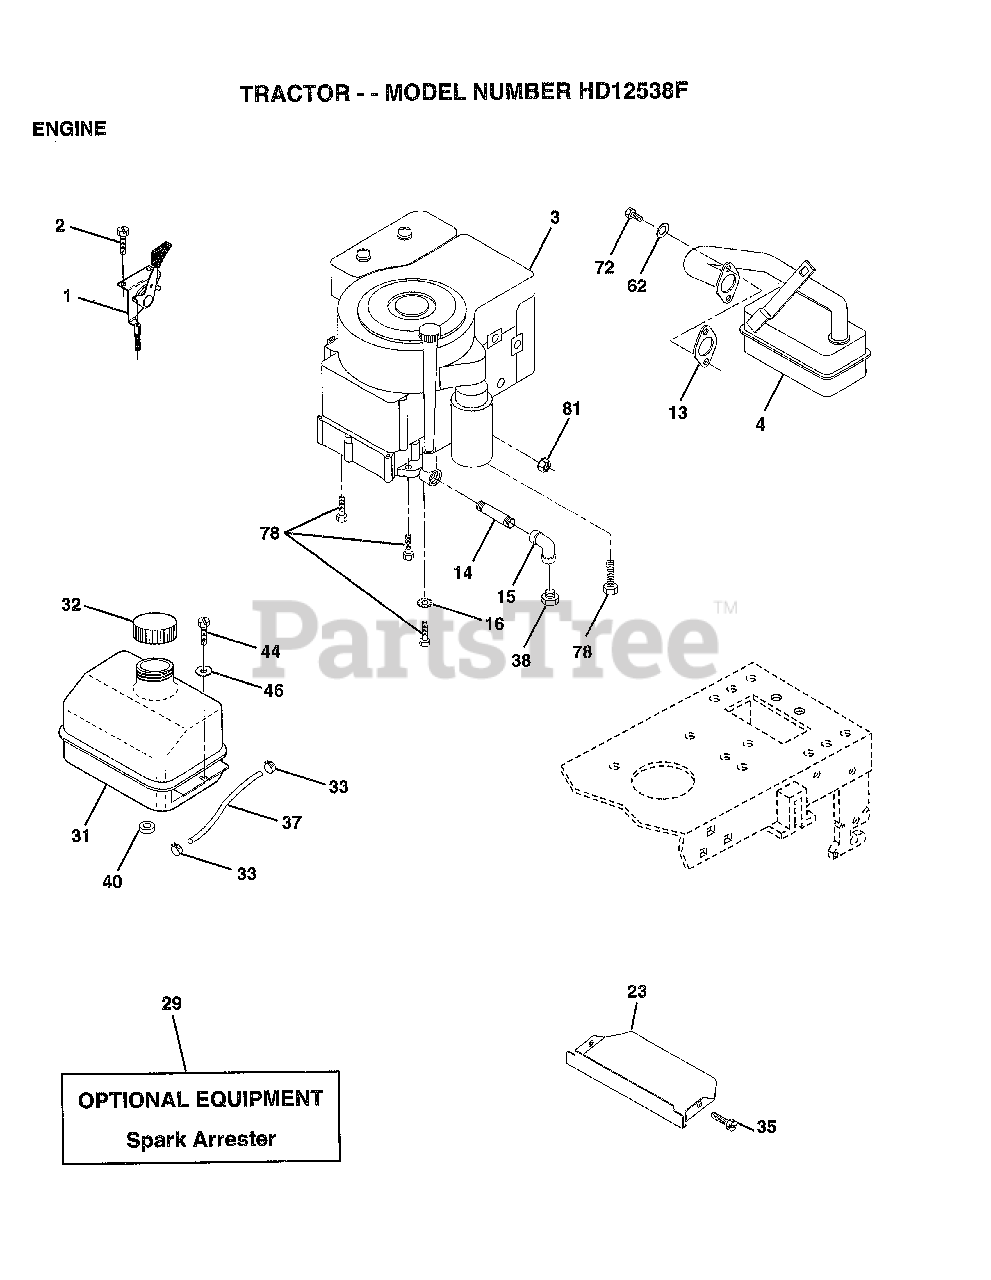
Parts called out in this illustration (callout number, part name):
1	CONTROL THROTTLE
2	SCREW LT
4	MUFFLER
13	GASKET ENG 1 313 LD TIN PLATED
14	PIPE NIPPLE
15	ELBOW
16	LOCKWASHER
23	SHIELD.BRN/DBR.GD
31	TANK.FUEL.LT.
32	CAP ASM FUEL
33	HOSE CLAMP
35	SCREW
37	LINE FUEL
44	SCREW HEX CRT
46	WASHER
62	LOCKWASHER
72	SCREW
78	SCREW
81	NUT
